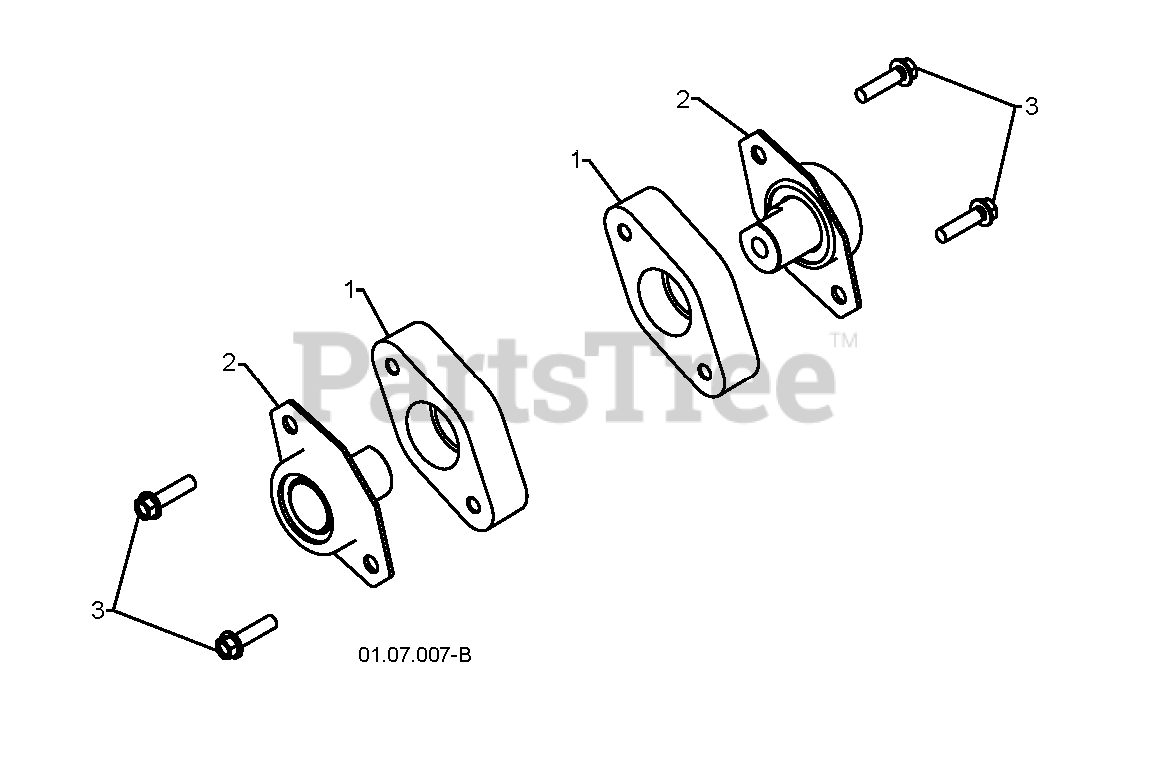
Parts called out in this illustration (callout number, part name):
1	RETAINER.PLASTIC
2	BEARING.BALL.AUGER
3	SCREW, HEX HD 5/16X1
